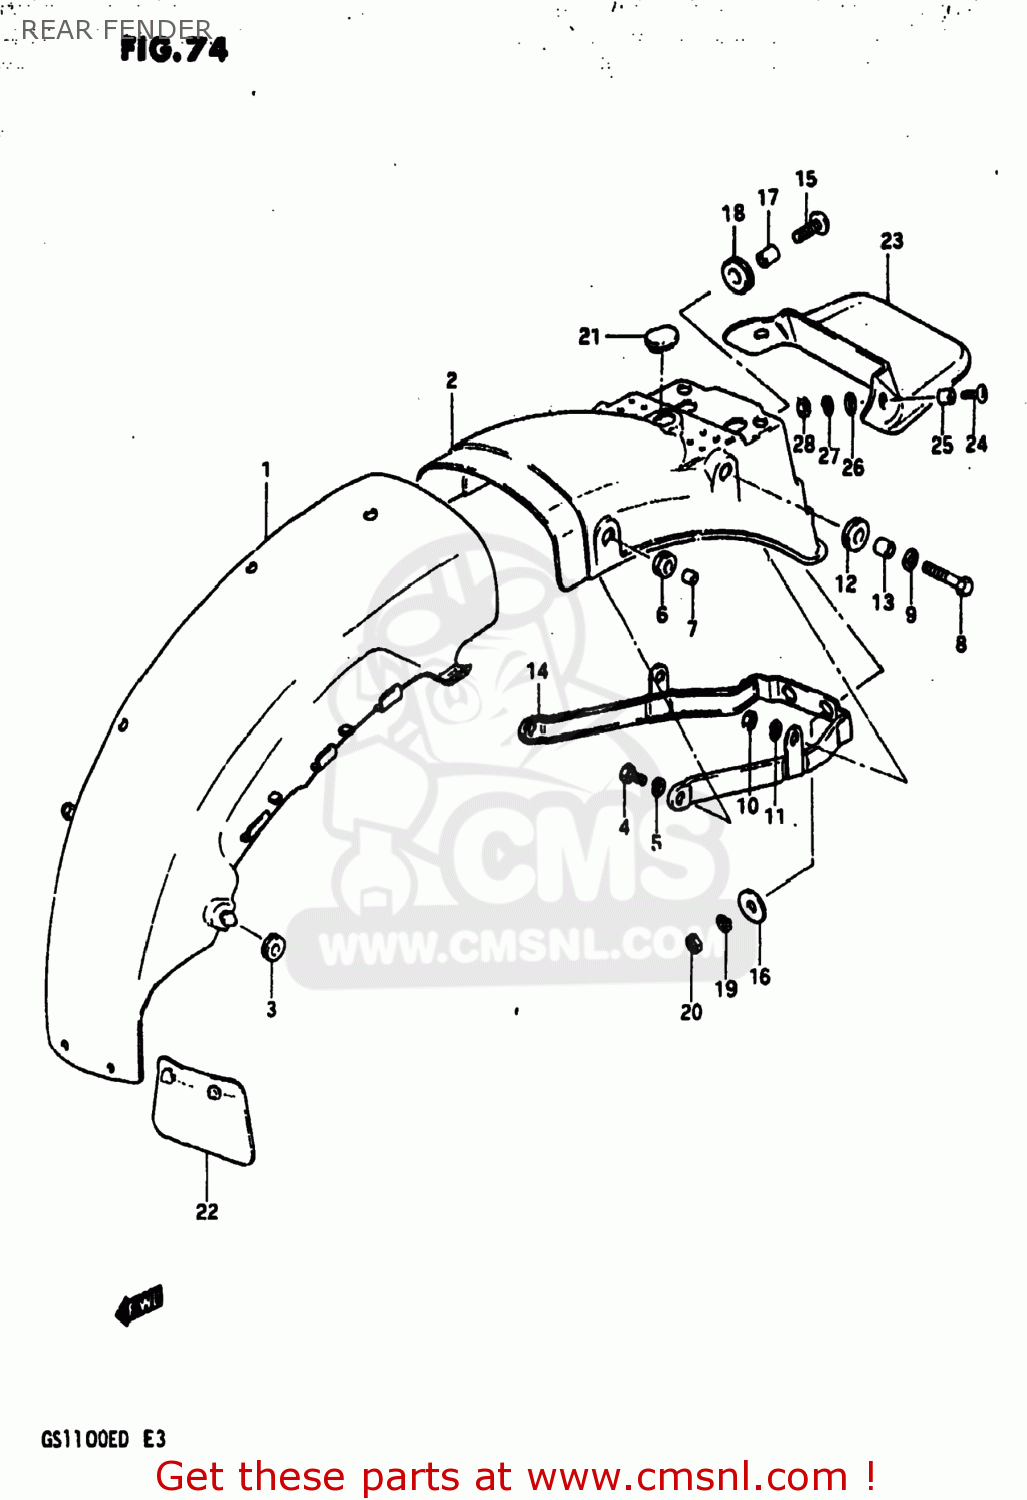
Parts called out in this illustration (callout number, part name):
1	FENDER,REAR
2	BODY,RR FENDER RR
3	CUSHION
4	BOLT
5	LOCK WASHER
6	CUSHION
7	SPACER(6.1X9X7.5)
8	BOLT
9	WASHER
10	NUT
11	LOCK WASHER
12	CUSHION
13	SPACER (8.2X12X7.5)
14	REINFORCEMENT,REAR FENDER
15	SCREW
16	WASHER(6,5X22X1.6)
17	SPACER (6.1X9X9)
18	CUSHION
19	LOCK WASHER
20	NUT
21	CAP
22	GUIDE,RR FENDER MUD
23	EXTENSION,REAR FENDER
24	SCREW (6X15)
25	SPACER(6.2X8.3X5.7)
26	WASHER(6.5X18X1)
27	LOCK WASHER
28	NUT
